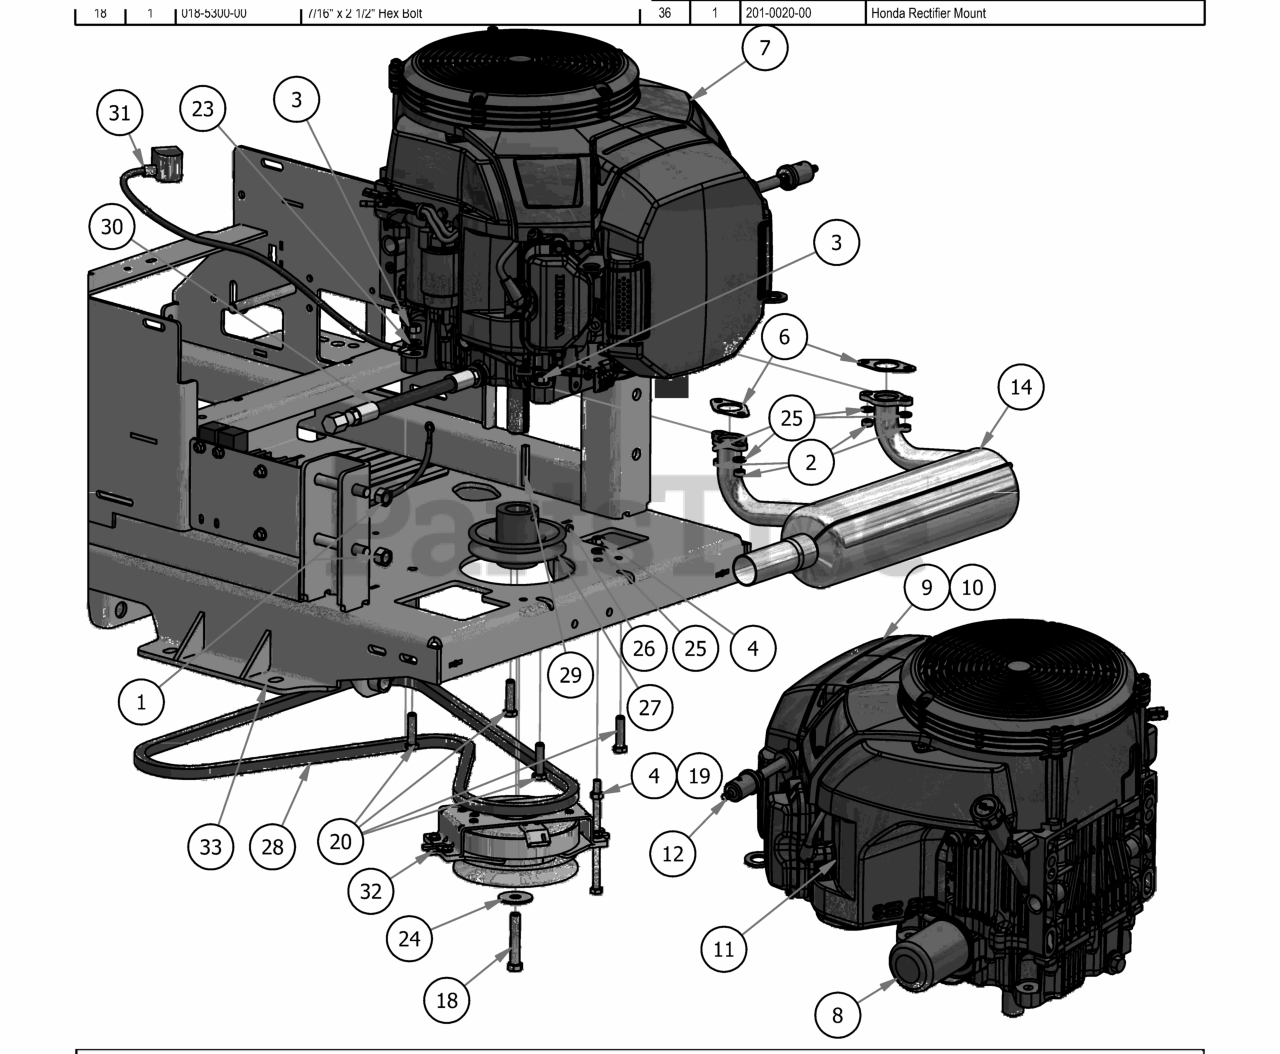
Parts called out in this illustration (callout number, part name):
1	1/2" Center Lock Nut
2	M8-1.25 Zinc Nut
3	3/8" Hex Nut
5	1/4-20 Hex Flange Nuts Zinc w/Serrations
6	Exhaust Gasket
7	2019 Honda Engine
8	Oil Filter
9	Pre-Cleaner
10	Air Cleaner Element
11	Spark Plug
12	Fuel Flilter
13	Regulator Rectifier for Honda Engine
14	2019 Honda Maverick Muffler
15	M6-1.0 X 16MM Hex Bolt
16	1/4" x 1/2" BS C/S 18-8 SS
17	1/4-20 x 1 GR 5 hex bolt zinc
18	7/16" x 2 1/2" Hex Bolt
19	5/16-18 x 5-1/2 GR 5 Hex Bolt
20	3/8 x 1.5" Bolt
21	1/2-13 x 3 1/2 GR 5 Hex Bolt
22	1/4" Lock Washer
23	3/8" Lock Washer
24	1/2" Belleville Washer
25	5/16" Lock Washer
26	5/16 Set Screw
27	4 3/4 Motor Pulley
28	75.8" Pump Belt
29	1/4 x 2 Square key Stock
30	Honda Oil Drain
31	Ground Cable
33	2018 Maverick Frame
34	Relay Terminal
35	Wiring Harness
36	Honda Rectifier Mount
